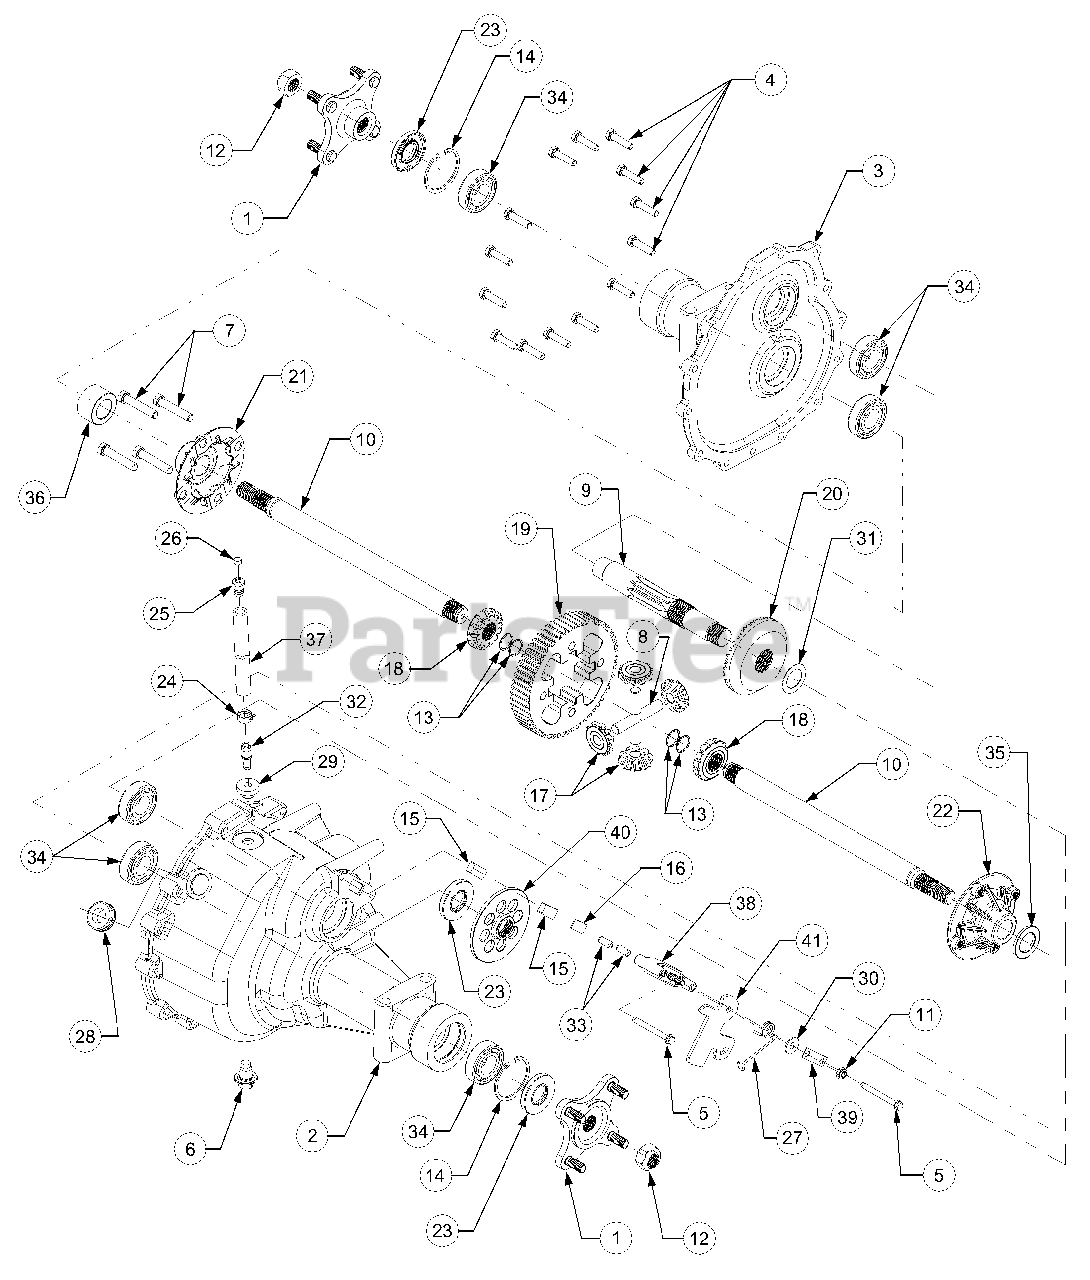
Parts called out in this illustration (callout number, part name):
1	Hub Assembly, Wheel
2	Housing, RH Transmission
3	Housing, LH Transmission
4	Screw, Hex Cap Lock, 5/16-18 x 1.25 GR5
5	Screw, Hex Wash Hd. Tapp, 1/4-20 x 2.375
6	Screw, Plug, M14 x 1.5 x .827
7	Screw, Hex Cap Lock, 3/8-24 x 2.0 GR5
8	Shaft, Cross, .50 x 3.005
9	Shaft, Output, 9T
10	Shaft, Axle
11	Nut, Hex Nylon Lock, 5/16-24
12	Nut, Hex, 3/4-16
13	Ring, Retaining, .75
14	Ring, Retaining
15	Pad, Brake
16	Plate, Puck
17	Gear, Miter, 10T
18	Gear, Miter, 14T
19	Gear, Differential Spur, 60T
20	Gear, Bevel, 54T
21	Housing, Differential w/Thru Holes
22	Housing, Differential w/Threads
23	Seal, Oil, 1.0 x 2.047 x .2755
24	Clamp, Hose
25	Vent, Plastic
26	Cap, Plastic Vent
27	Spring, Torsion
28	Grommet, Rubber, .75 x 1.063
29	Grommet, Rubber, .362 x .56
30	Washer, Flat, .343 x .88 x .062
31	Washer, Thrust, 1.007 x 1.542 x .03
32	Fitting, Tube
33	Pin, Brake Actuating
34	Bearing, Ball (6205-1)
35	Spacer, Axle, 1.007 x 1.665 x .141
36	Spacer, Axle, 1.007 x 1.665 x .989
37	Tube, Transmission Breather
38	Yoke, Brake
39	Bracket, Brake Anti Rotation
40	Disc, Brake
41	Arm, Brake Actuater
